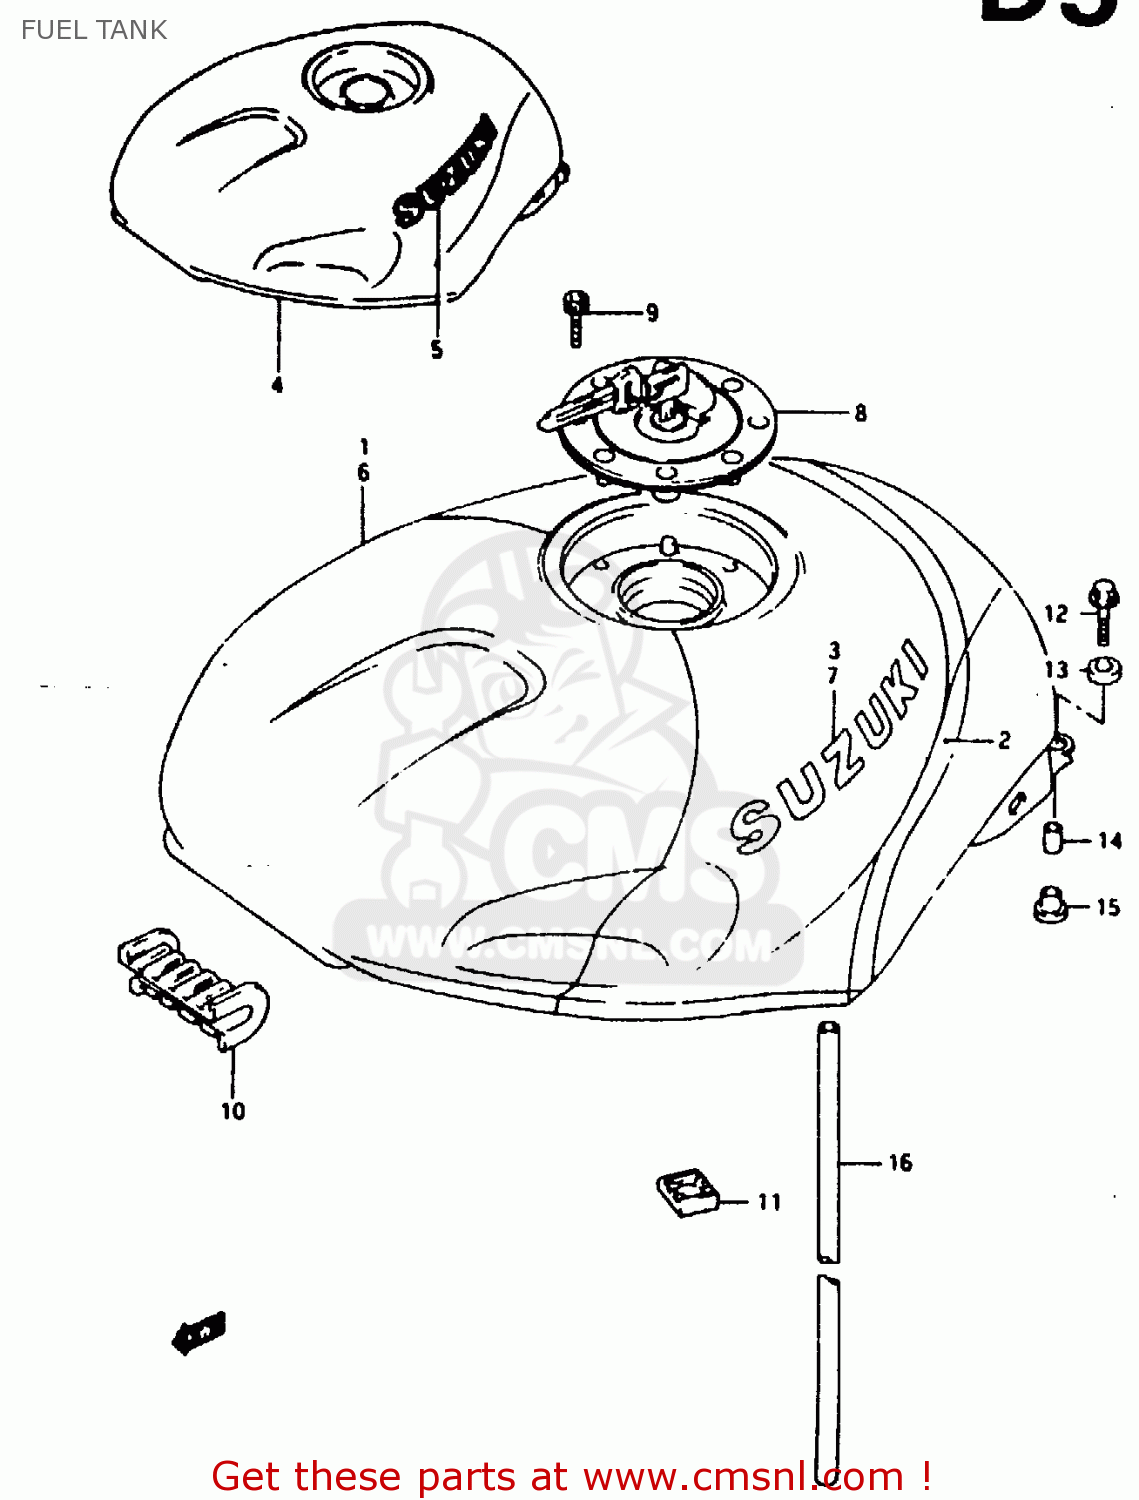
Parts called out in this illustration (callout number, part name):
1	TANK ASSY, FUEL
2	TAPE, FUEL TANK
3	EMBLEM,FUEL TANK(WHITE)
4	TANK ASSY, FUEL (BLACK)
5	EMBLEM
6	TANK ASSY, FUEL (BLUE)
7	EMBLEM (GRAY)
8	CAP SET,FUEL TANK
9	BOLT(5X20)
10	CUSHION,FUEL TANK,FRONT
11	CUSHION,FUEL TANK SIDE
12	BOLT
13	CUSHION
14	SPACER
15	CUSHION
16	HOSE (7X10.2X1000)
